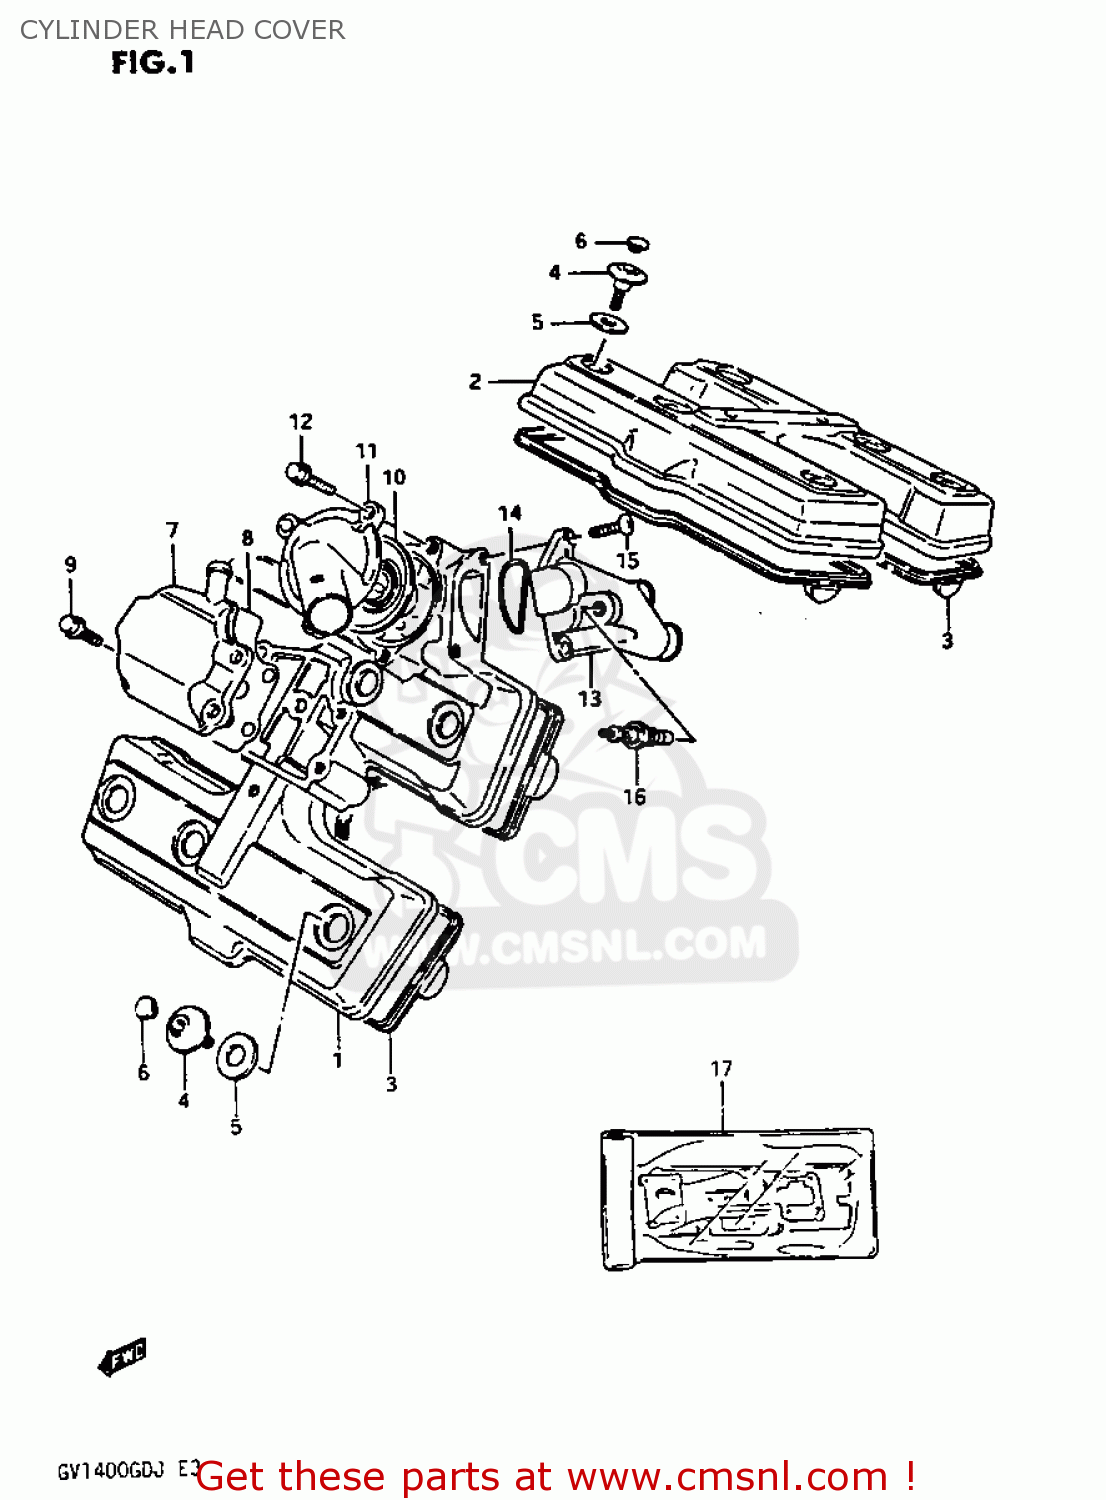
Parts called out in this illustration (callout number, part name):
1	COVER,CYLINDER HEAD,FRONT
2	COVER,CYLINDER HEAD,REAR
3	GASKET,CYLINDER HEAD COVER (NAS)
4	BOLT(7X5.5)
5	WASHER(10.6X25.5X2.3)
6	CAP(OD:10)
7	GASKET
8	GASKET,BREATHER COVER (NAS)
9	BOLT 6X20
10	THERMOSTAT,WATER
11	CAP,THERMOSTAT CASE
12	BOLT 6X20
13	CONNECTOR,THERMOSTAT,INLET
14	O-RING,THERMO CONNECTOR
15	SCREW
16	GAUGE ASSY,WATER TEMP
17	GASKET SET
